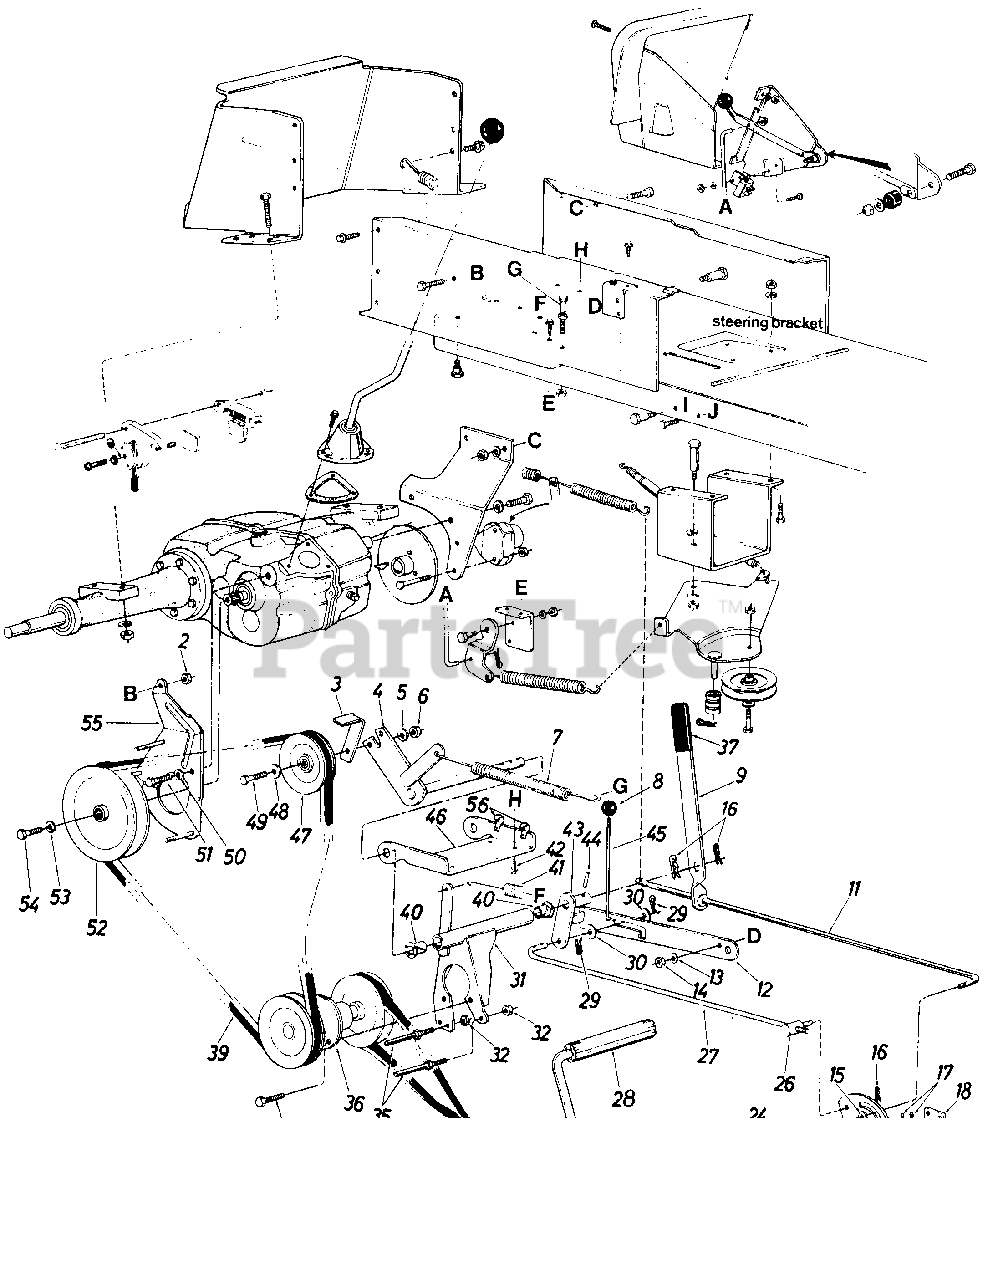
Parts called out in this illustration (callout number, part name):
2	Hex L-Nut 3/8-16 Thd.
5	L-Wash. 3/8" I.D.
6	Hex Nut 3/8-16 Thd.
7	Ext. Spring
8	Knob
9	Hand Brake Lever
11	Brake Rod
12	Parking Brake Cam
13	L-Wash 5/16" I.D.
14	Hex Nut 5/16-18 Thd.
15	Fl-Wash. 5/16" I.D.
16	Hairpin Cotter 3/8" Rod
17	Cotter Pin 1/8" Dia. x 1.00" Lg.
18	Clutch Rod Brg. Brkt.
19	Clutch Brake Pedal Ass'y.
20	Hex Cent. L-Nut 3/8-16 Thd.
22	Engine Pulley 4.75 & 5.56
24	Hex Cent. L-Nut 3/8-16 Thd.
25	Cotter Pin 3/32" Dia. x .75" Lg.
26	Pivot Bushing
27	Brake Cam Rod
28	Foot Pad
29	Hairpin Cotter 3/8" Rod
30	Fl-Wash. 3/8" I.D. x 1.00" O.D. x .030
31	Jack Shaft Mtg. Brkt. Ass'y.
32	Hex Top L-Nut 3/8-16 Thd.
34	"V"-Belt
35	Stud 3/8-16 x 3.62" Lg. Special
36	Jack Shaft Ass'y.
37	Flat Grip
38	Hex Sem Scr. 5/16-18 x .75" Lg.
39	"V"-Belt
40	Nyliner 5/8" I.D. x .88" Lg.
41	Ext. Spring
42	Hex Thd. Rolling Scr. 1/4-20 x .50" Lg.
43	Clutch-Idler Horn Ass'y.
44	Spring Pin Spiral 1/4" Dia. x 1.00" Lg.
45	Parking Brake Link
46	Idler Mtg. Brkt. Drive
47	4" "V"-Idler Pulley
48	Fl-Wash. 3/8" I.D.
49	Hex Bolt 3/8-16 x 1.75" Lg.
50	L-Wash. 3/8" I.D.
51	Hex Bolt 3/8-16 x .75" Lg.
52	"V"-Pulley 7.0" O.D.
53	L-Wash. 3/8" I.D.
54	Hex Scr. 3/8-24 x .75" Lg.
55	Belt Guard Ass'y.
56	Plastic Hose Clamp
